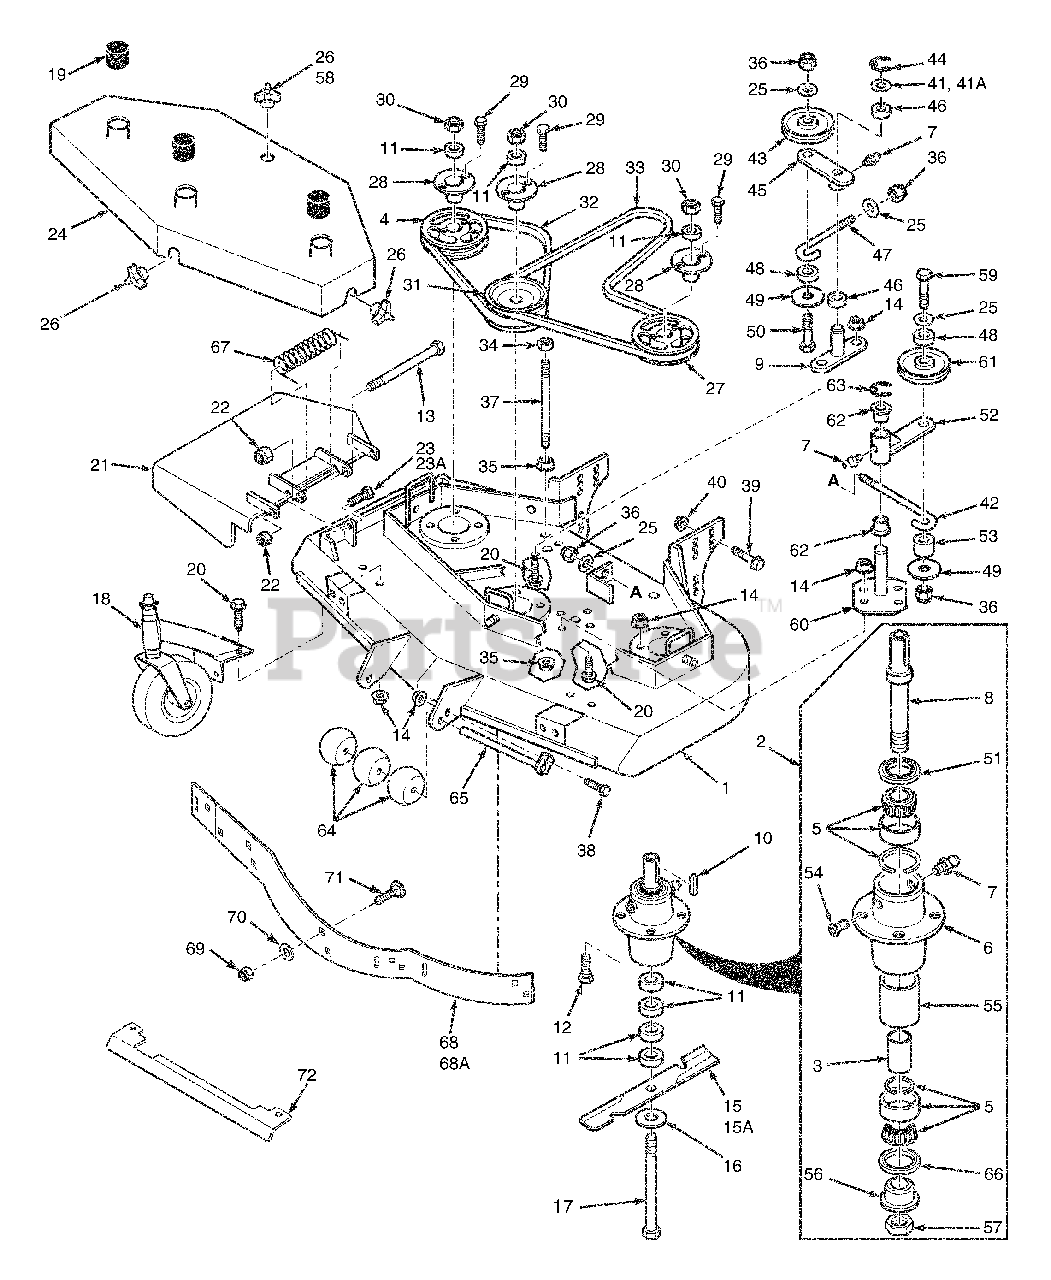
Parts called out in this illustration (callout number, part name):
1	Cutter Deck
2	Spindle Assembly
3	Spacer, Inside
4	Pulley
5	Tapered Bearing (Two)
6	Spindle Housing
7	Grease Fitting Str. 5/16"
8	Spindle Shaft, Tapered Brng
9	Idler Pivot
10	Key, 1/4 x 1/4 x 2"
11	Spacer, Cutter Blade - Small
12	Bolt, 5/16-18 x 1-1/4" Hex Head
13	Bolt, 5/16-18 x 4-3/4" Hex Head
14	Serrated Flange Nut, 5/16-18
15	Cutter Blade 16-1/2" Marbain
15A	Cutter Blade 16-1/2 High Lift Marbain
16	Flatwasher,5/8" (.688 x 1.75 x .134)
17	Hex Head Bolt, 5/8-11 x 9-1/2"
18	Caster Assembly
19	Spindle Shield
20	Capscrew, 5/16-18 x 3/4"
21	Discharge Chute
22	Nut, 5/16-18 Elastic Elastic Stop
23	Bolt, 5/16-18 x 1-1/2" Hex Head (Front)
23A	Bolt, 5/16-18 x 1-3/4" Hex Head (Rear)
24	Belt Cover
25	Flat Washer, 3/8" Special
26	Wing Nut, 3/8-16 (Large)
27	Pulley
28	Tapered Hub
29	Bolt, 1/4-20 x 3/4" Hex Head
30	Nut, 5/8-11 Hex
31	Pulley, Double
32	Belt, RH Blade Drive
33	Belt, Blade Drive
34	Nut, 3/8-16, Nut Centerlock
35	Nut, 3/8-16, Serrated Flange
36	Nut, 3/8-16 Elastic Stop
37	Support, Belt Cover
38	Bolt, 5/16-18 x 1" Hex Head
39	Cpscrw, 1/2-13 x 1" Ser.Flg. HH
40	Nut, 1/2-13 Spiralock
41	Flat Washer 3/4" Special
41A	Flat Washer 3/4" Special
42	J-Hook
43	Idler Pulley, "V" Groove
44	Retaining Ring, 3/4" Ext."E"
45	Idler Arm Assy.
46	Bronze Bearing
47	J-Rod, Idler Pulley
48	Spacer, J-Rod
49	Washer, 3/8 x 1-1/2 x 16 ga.
50	Bolt, 3/8-16 x 2-1/4" Hex Head
52	Seal, Cutter Spindle
52	Idler Arm Assy
53	Spacer, J-Rod
54	Relief Fitting, Cutter Spindle
55	Spacer, Outside, Cutter Spindle
56	Spindle Bushing
57	Nut, Cutter Spindle
58	Wing Nut, 3/8-16 (Small) Top Side
59	Bolt, 3/8-16 x 3-1/2" Hex Head
60	Idler Pivot
61	Idler Pulley, Belt Clutch
62	Bronze Bearing
63	Retaining Ring
64	Guide Roller
65	Roller Shaft
66	Seal, Cutter Spindle
67	Spring, Chute Return
68	Baffle Weldment 48A
69	Nut, Hex Elastic Stop 3/8-16
70	Flatwasher, 3/8" (.391 x .938 x .105)
71	Bolt, Carriage 3/8-16 x 1"
72	Heatshield
